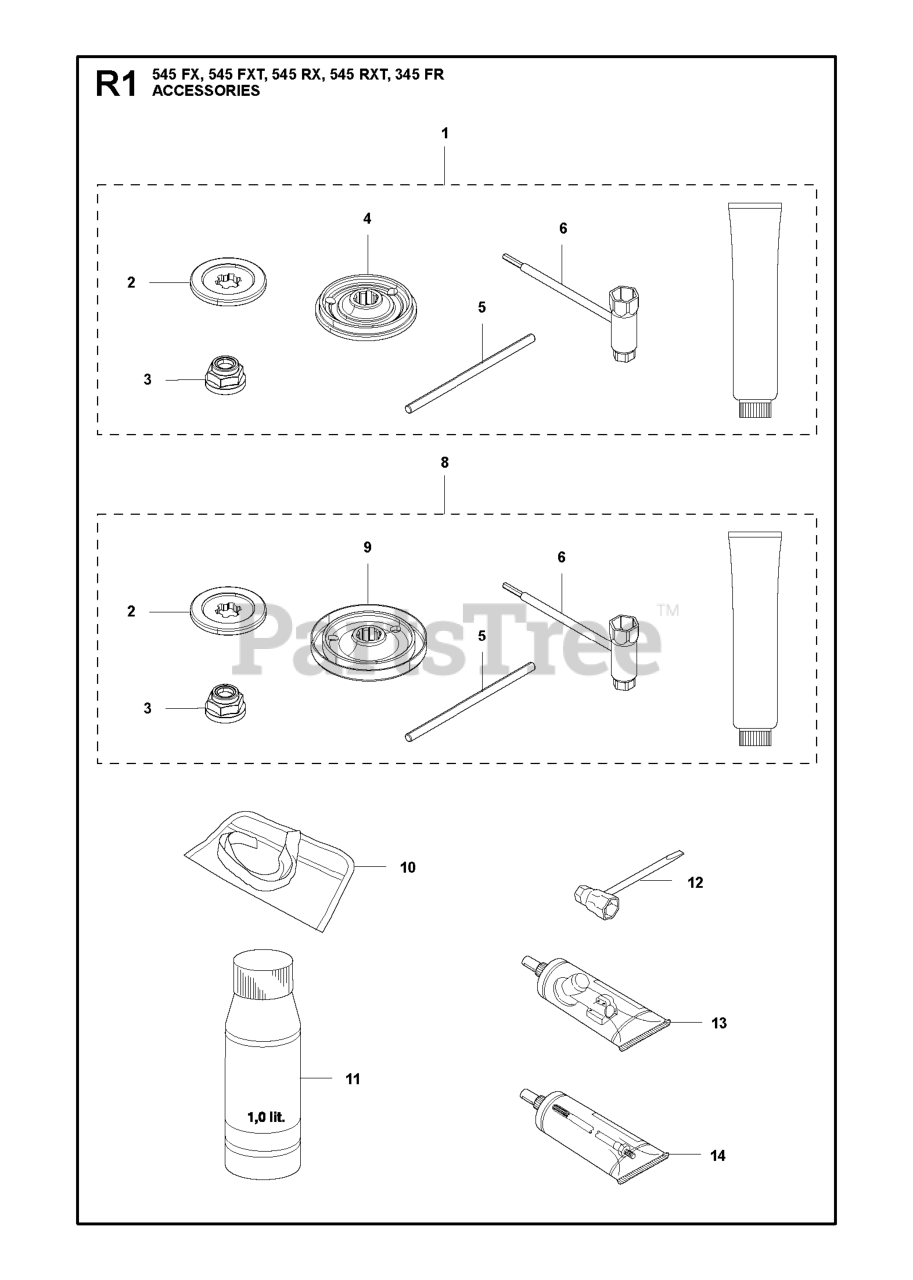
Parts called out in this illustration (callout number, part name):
1	ACCESSORY BAG
5	LOCKING PIN
6	COMBINATION WRENCH
8	ACCESSORY BAG
11	Air Filter Oil 1l.
12	RP COMBI TOOL
13	BEVEL GEAR GREASE
14	DRIVE SHAFT GREASE (200 G)
